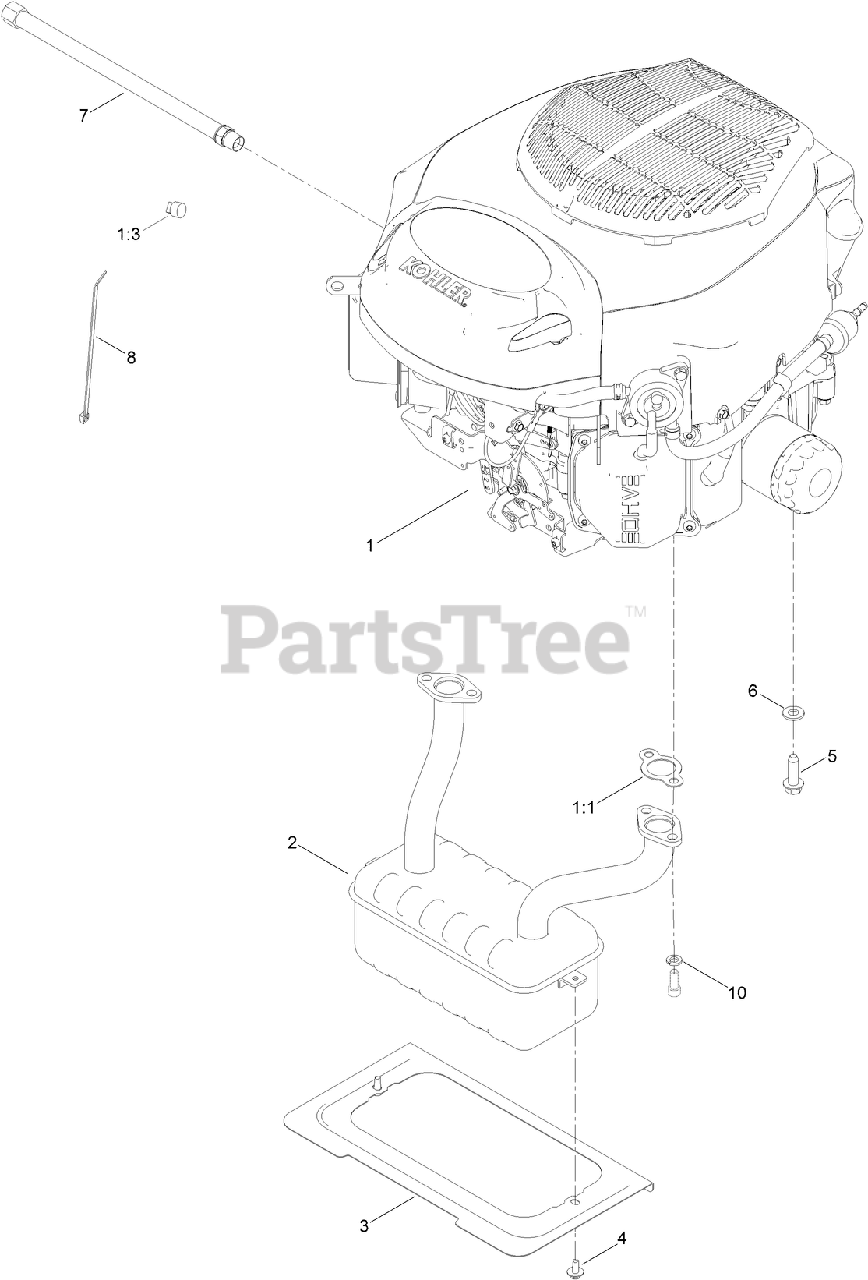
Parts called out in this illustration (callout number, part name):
1	ENGINE-KOHLER 22 HP 7000 SERIES CARB
1:1	GASKET-EXHAUST
1:3	PLUG-PIPE, SQH
2	MUFFLER
3	SHIELD-HEAT
4	SCREW-HHFTF
5	SCREW-THD
6	WASHER-FLAT
7	HOSE-DRAIN, OIL
8	TIE-CABLE
10	WASHER-LOCK
